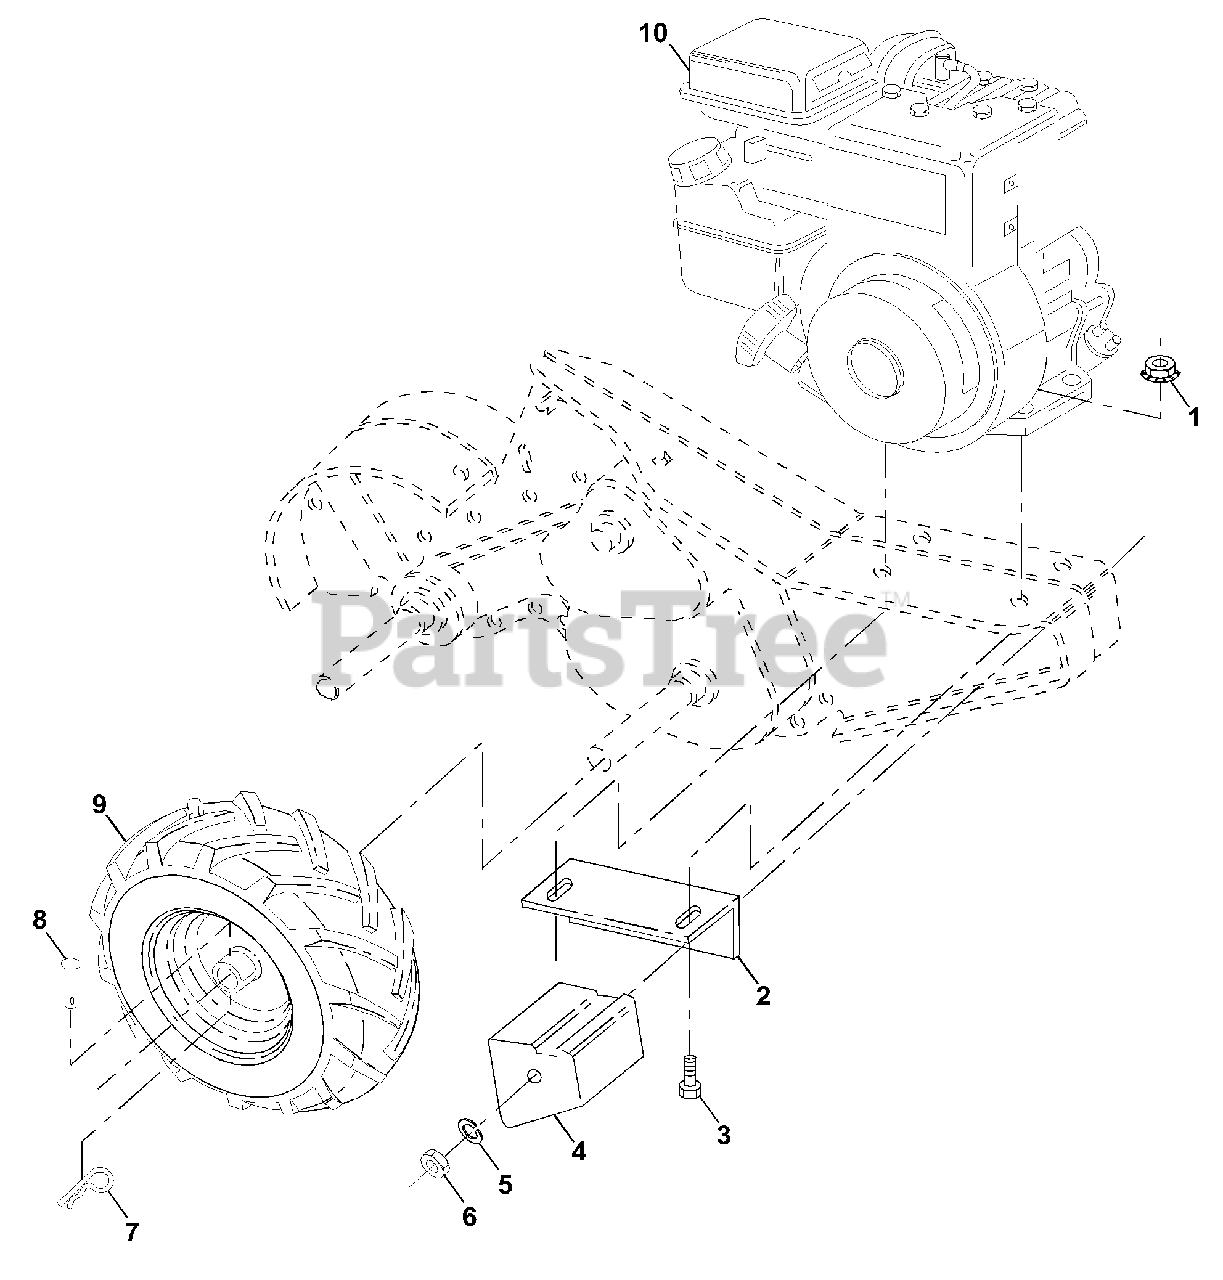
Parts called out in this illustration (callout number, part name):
1	Nut, Keps 5/16-18
2	Bracket, Reinforcement
3	Bolt, Hex 5/16-18 x 1-1/2
4	Counter Weight, R.H.
5	Washer, Lock 3/8
6	Nut, Hex 3/8-16
7	Clip, Hairpin
8	Rivet, Drilled
9	Rim
9	Tire Valve
10	Engine, Briggs & Stratton
